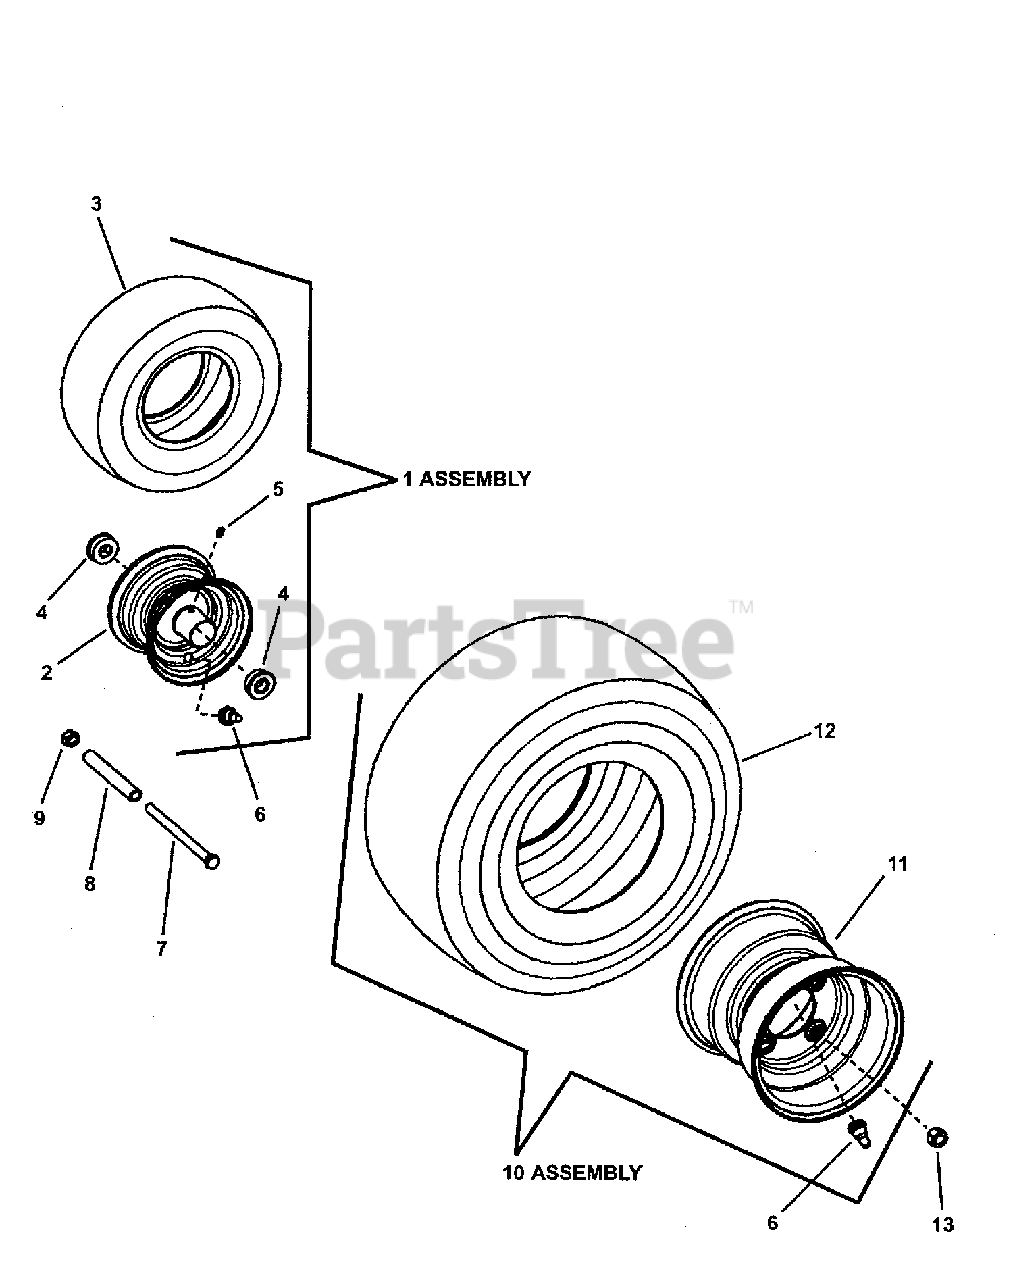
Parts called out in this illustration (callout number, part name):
1	ASSEMBLY, Front Wheel & Tire
2	RIM, Caster Wheel
3	TIRE, 11 x 4.00-5, Smooth Tread
4	BALL BEARING, .625 x 1.38
5	FITTING, Lube (45° 8Mx1M)
6	VALVE STEM, Snap In
7	SCREW, 7/16-14 x 6", Hex Head Cap, GR 5
8	TUBE, 5/8 O.D. x 14 Ga. Wall x 4.510" long
9	NUT, 7/16-14 Hex Center Lock, GR 5 or B
10	ASS'Y. 18 x 8.50-8 Tire/Wheel, Turf Master, PMS 877 Silver
11	RIM, 18 x 8.50, 4 Bolt
12	TIRE, 18 x 8.50-8, Turf Master
13	LUG NUT 1/2-20 Tapered Seat YZ
